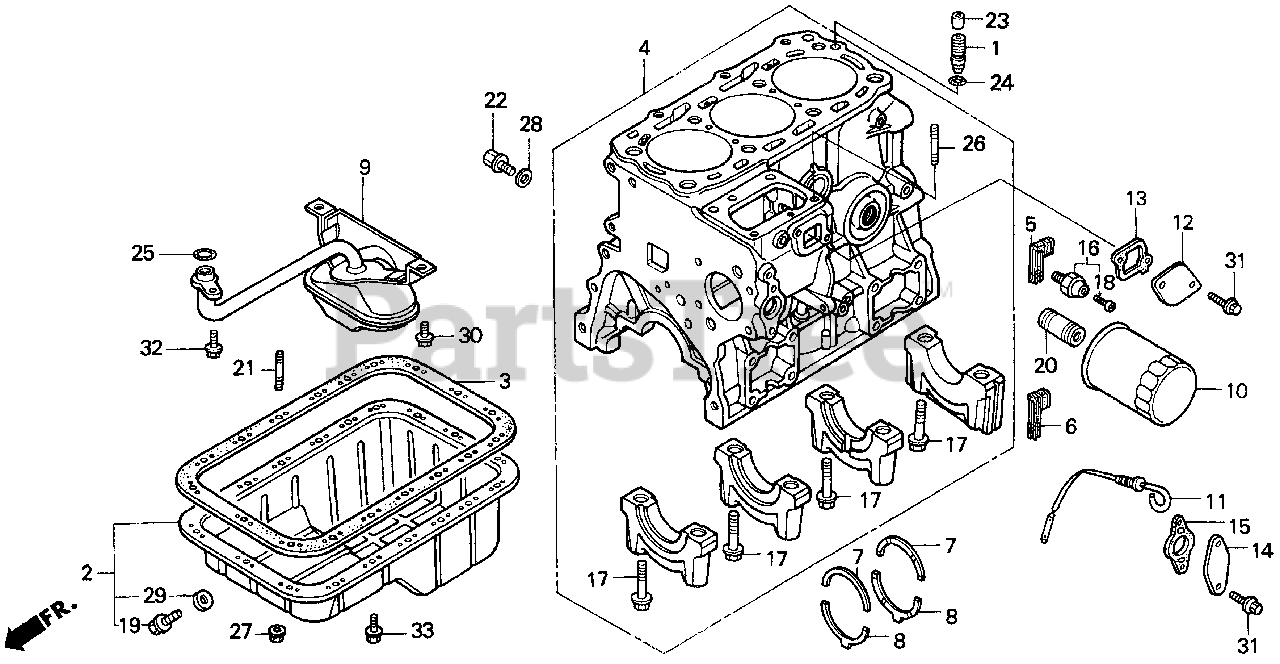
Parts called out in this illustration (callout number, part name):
1	ORIFICE, OIL CONTROL
3	GASKET, OIL PAN
4	BLOCK ASSY., CYLINDER
5	RUBBER, R. SIDE SEAL
6	RUBBER, L. SIDE SEAL
7	BEARING A, CRANKSHAFT THRUST
8	BEARING B, CRANKSHAFT THRUST
9	STRAINER, OIL
10	FILTER, OIL (FILTECH TOYO ROKI) (SOLD INDIVIDUALLY)
10	FILTER, OIL (SOLD INDIVIDUALLY)
11	DIPSTICK, OIL
12	COVER, RACK
13	GASKET, RACK COVER (NON-ASBESTOS)
14	COVER, FUEL PUMP CAM
15	GASKET, FUEL PUMP CAM COVER (NON-ASBESTOS)
16	SWITCH, OIL PRESSURE
17	BOLT, FLANGE (11X69)
18	SCREW-WASHER (4X8)
19	BOLT, DRAIN PLUG (14MM)
20	HOLDER, OIL FILTER
21	BOLT, STUD (6X28)
22	BOLT, DRAIN PLUG (12MM)
23	PIN, DOWEL (14X16)
24	O-RING (6.5X1.5)
25	O-RING (17.0X2.5) (ARAI)
26	BOLT 2, STUD (8X22)
27	NUT, FLANGE (6MM)
28	WASHER, DRAIN PLUG (12MM)
29	WASHER, DRAIN PLUG (14MM)
30	BOLT, FLANGE (6X10)
31	BOLT, FLANGE (6X14)
32	BOLT, FLANGE (6X16)
33	BOLT, FLANGE (6X18)
